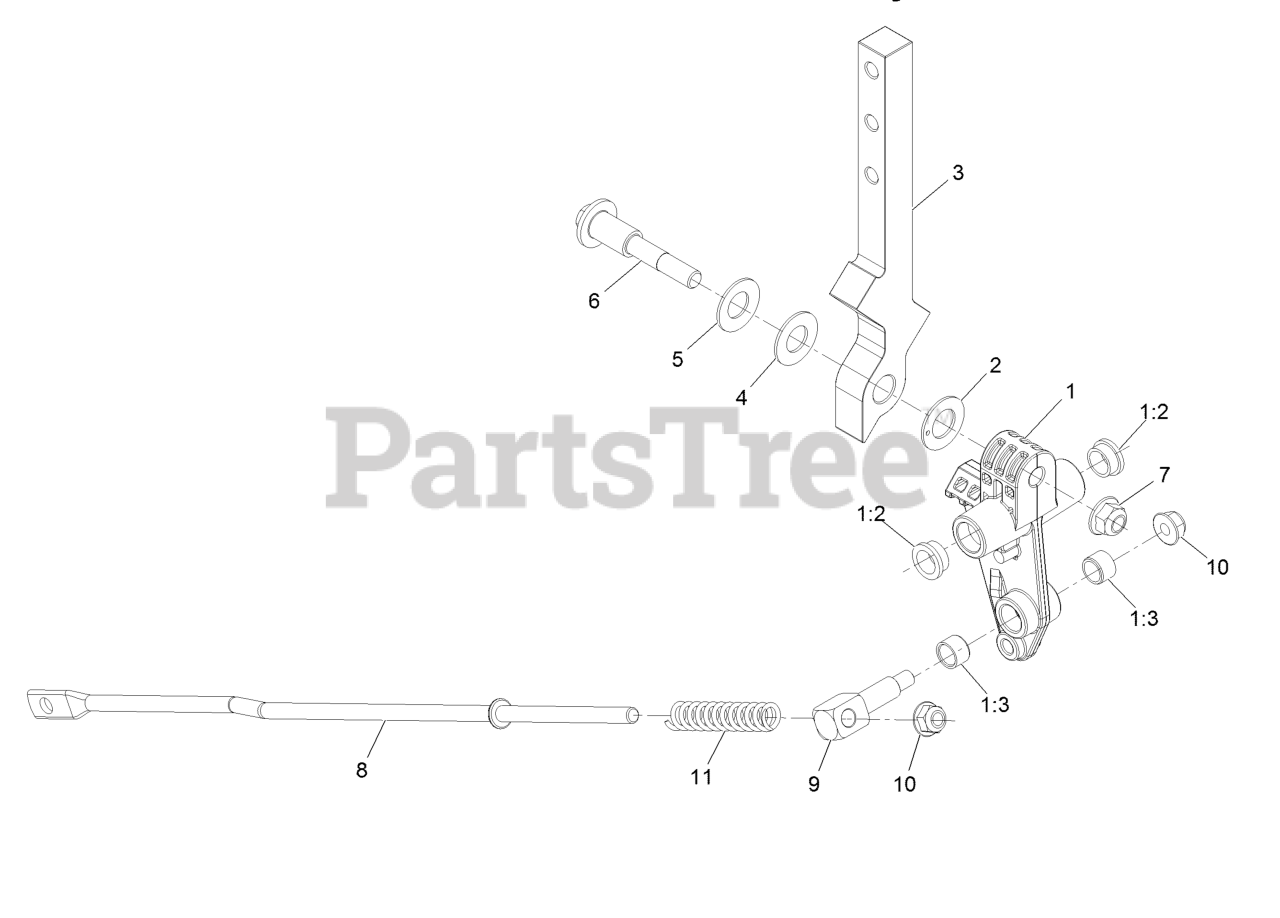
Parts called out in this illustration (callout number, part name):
1	Control Arm ASM
1:2	Bushing
1:3	Bushing-Sleeve
2	Washer-Friction
3	Arm-Control
5	Washer-Belleville
6	Bolt-Pivot
7	Nut-Nyloc 3/8-16 Flg
8	Link-Control
10	Nut-Nyloc 5/16-18 Flg
11	Spring-Return, Neutral
